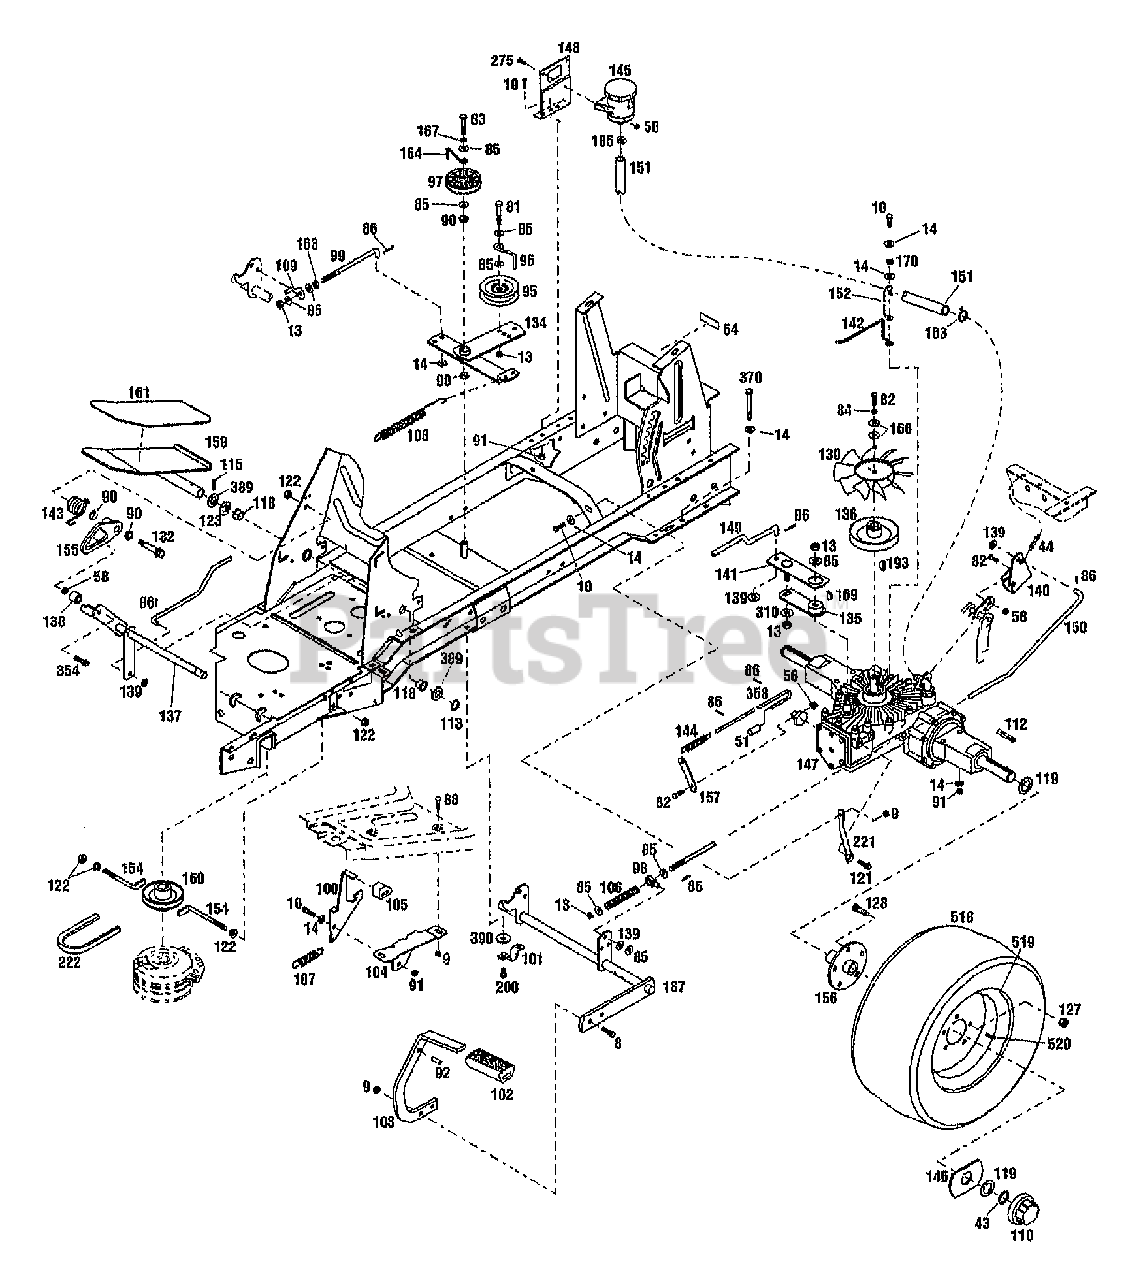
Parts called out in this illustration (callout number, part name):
8	SCR-HH 5/16-18X1.0 G5 ZP
9	NUT-HFLK 5/16-18 ZP
10	SCR-HHC 5/16-18X.75 GR 5 ZP
13	NUT-LOCK 3/8-16
14	WASHER-FLAT 5/16 SAE
43	RING-HEAVY EXT HD 1.0 ID
44	SPRING-EXTENSION
51	GRIP-HANDLE
54	DECAL-TRANS RELEASE
56	NUT-HF/LK 1/4-20 ZP
58	NUT-HT LK 1/4-20
81	SCR-HH 3/8-16X2.0 G5 ZP
82	SCR-HH 1/4-20X1.0
83	SCR-HH 3/8-16X1.75 G5 ZP
84	WASHER-LK .25 ZP
85	WASHER-FLAT 3/8 SAE
86	PIN-COTTER .09X.75 ZP
88	SCR-CARR 5/16-18X.62 G2 ZP
90	BUSHING-.5X.5 NYLON FLNG
91	NUT-TOP/LK 5/16-18 ZP
92	PIN-DRIVE .312X.75
96	GUIDE-BELT
97	PULLEY-IDLER
98	SWIVEL
99	ROD-CLUTCH
100	LATCH-BRAKE LOCK
101	CLIP-CLAMP .75 ID
102	PAD-FOOT PEDAL
103	PEDAL-BRAKE
104	BRKT-BRAKE LOCK
105	PAD-BRAKE
106	SPRING-COMPRESSION
107	SPRING-EXTENSION
108	SPRING-EXTENSION
109	ROD-PIVOT
110	CAP-HUB
112	KEY-.25 SQ X 2.0
113	RING-RETAIN .625 ID
115	PIN-ROLL .188X1.0
118	BEARING-FLANGE
119	WASHER-SPEC
121	SCR-HFLK 5/16-18X.50 ZP
122	NUT-HFLK 3/8-16 ZP
123	WASHER-1.115X.637X.06
127	NUT-LUG 7/16-20
128	BOLT-WHEEL
130	FAN-HYDRO TRANSMISSION
132	SCR-SHLDR 3/8-16
134	ARM-IDLER
135	ARM-HYDRO
136	PULLEY-HYDRO
137	SHAFT-HYDRO PIVOT
138	BEARING-BALL
139	WASHER-FLAT .375DIA
140	BRKT-BRAKE HYDRO
141	ARM-CONTROL HYDRO
142	GUIDE-BELT
143	SPRING-TORSION
144	SPRING
145	TANK-EXPANSION
146	WASHER-SPECIAL .75X2.5
147	TRANSMISSION
148	SUPT-EXPANSION TANK
149	ROD-CONTROL HYDRO
150	ROD-BRAKE
152	SUPPORT-HOSE
153	CLAMP-HOSE 5/8
154	RETAINER-CLUTCH
155	ARM-RETURN NEUTRAL HYDRO
156	HUB-WHEEL
157	VALVE-DUMP
158	ASSM-PEDAL HYDRO
160	PULLEY-ENGINE
161	PAD-FOOT PEDAL
163	NUT-HEX 3/8-16 ZP
164	GUIDE-BELT
166	WASHER-FLAT 1.25X.28X.062 ZP
167	WASHER-LK .375 @ DEPL
169	KEY-WOODRUFF .125X.5
170	WASHER-LK .312 ZP
185	CLAMP-HOSE
187	ASSM-BRAKE PEDAL
193	KEY-WOODRUFF
200	SCR-HFLK 5/16-18X.75
221	SUPPORT-TRANSMISSION
275	SCR-HH 1/4-20X.625 G5 ZP
310	WASHER-LK .375 PYRAMIDAL
354	SCR-HFLK 1/4-20X1.25 G5ZP
358	ROD-DUMP VALVE
370	SCR-HH 5/16-18X3.0
389	WASHER-SHIM
390	WASHER-.632X.39X.0329
519	RIM-WHEEL REAR
520	STEM-VALVE
